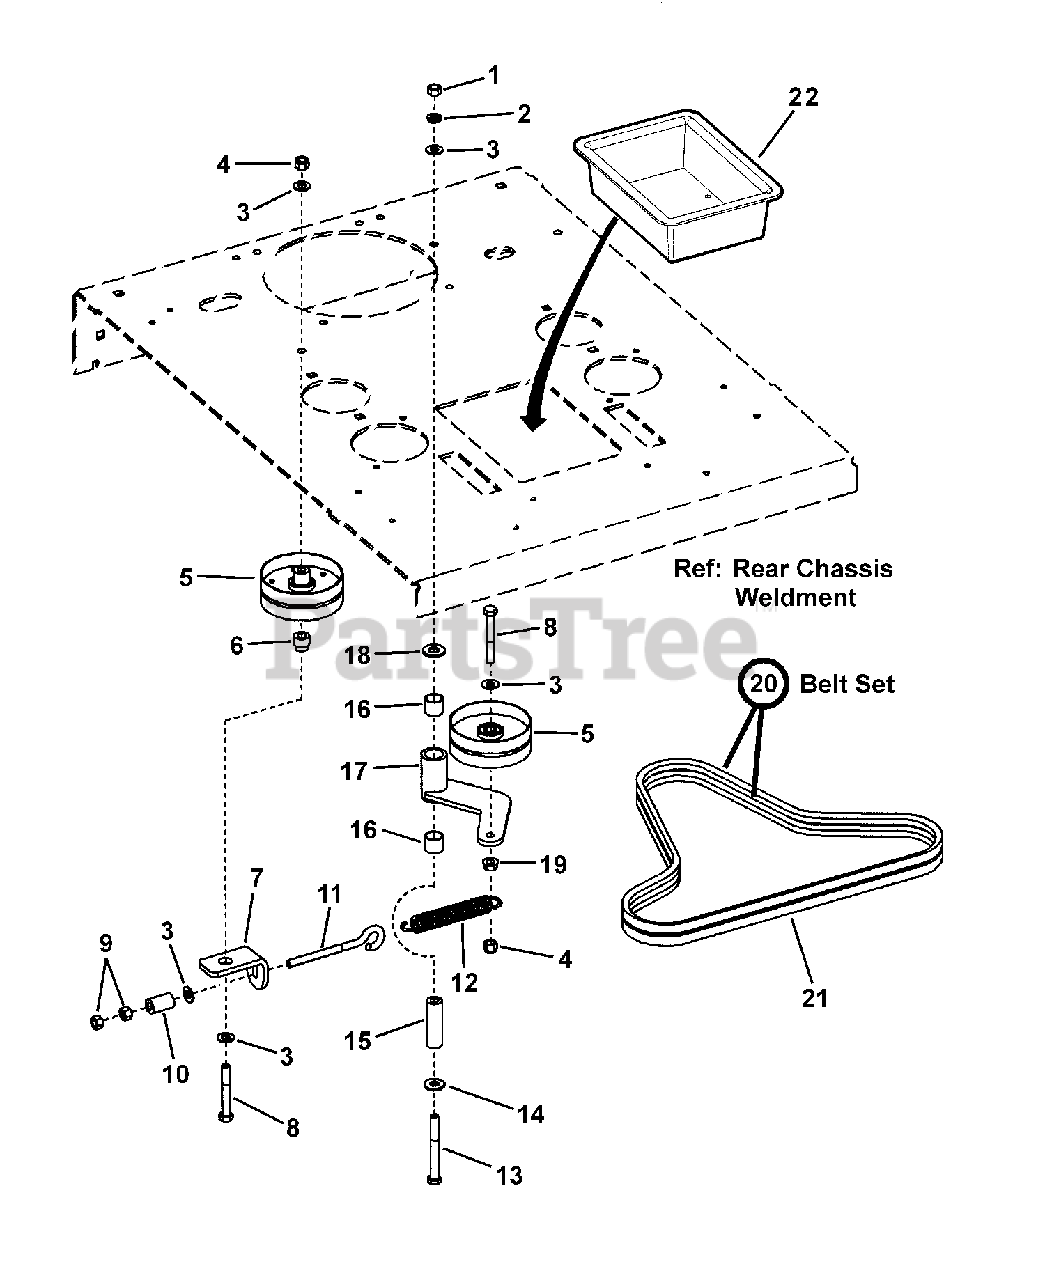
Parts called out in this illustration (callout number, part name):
1	NUT, 3/8-16 Hex, GR 5 or B
2	WASHER, 3/8" Split Lock
3	WASHER, 3/8" Flat SAE
4	NUT, 3/8-16 HEX NYLON LOCK
5	PULLEY, 4" O.D. x .391 I.D. x 1.25 Backside Idler
6	SPACER, Pulley
7	MOUNT, Idler Spring
8	BOLT, 3/8-16 X 2-3/4" GD5 CZ
9	NUT, 3/8-16 Hex, GR 5 or B
10	SPACER, Lift Adjust (1.08" Long)
11	EYEBOLT, 3/8-16 x 3"
12	SPRING, Extension
13	BOLT, 3/8-16 x 3-1/2" Hex Head, GR 5
14	WASHER, 3/8" USS
15	BOSS, IDLER,YELLOW GV3036304
16	BUSHING, SLEEVE, 3/4 ID, GV3031224
17	WELDMENT, Drive Idler
18	WASHER, .531 I.D. Flat
19	NUT, 3/8-16 HEX SERRATED FLANGE
20	SET, Matched Traction Drive Belt
21	BELT, HA Sect., 54.48" effective length
22	TRAY, Battery (Polypropylene)
